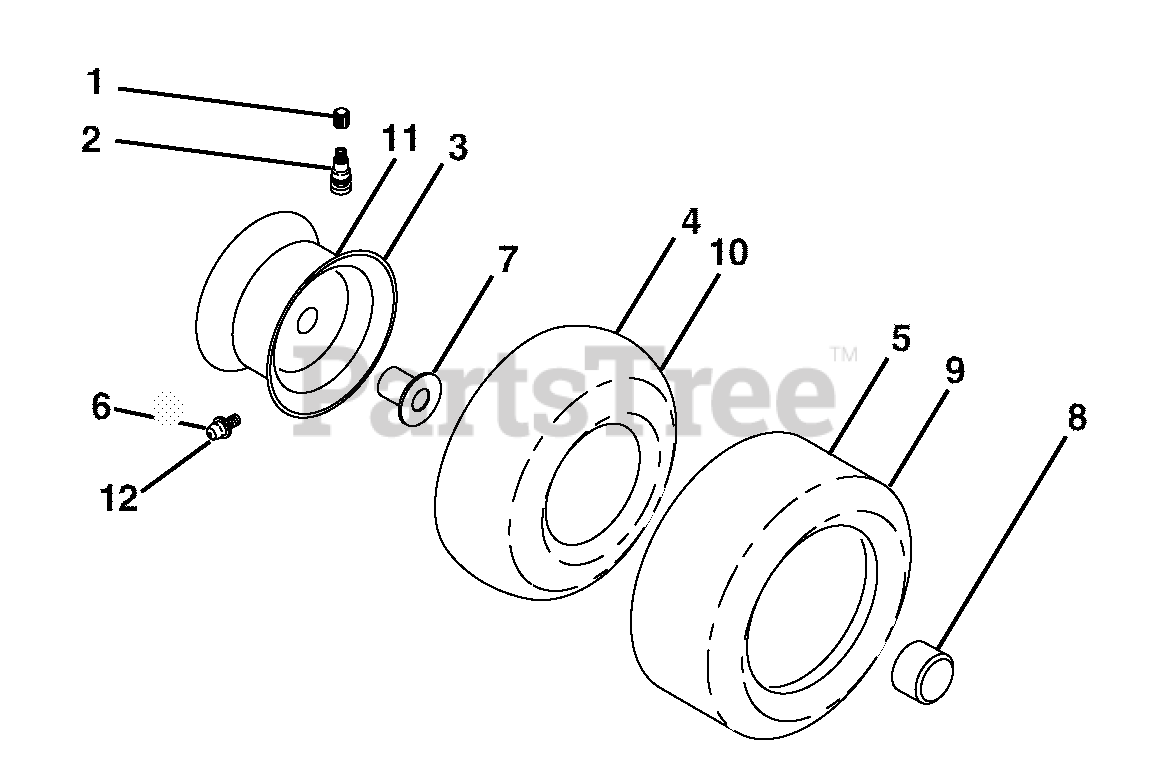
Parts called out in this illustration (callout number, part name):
1	Cap, Valve, Tire
2	Stem, Valve
3	Rim Assembly, Front
4	Tube, Front
5	Tire, Front
6	Fitting, Grease
7	Bearing, Flange
8	Cap, Hub
9	Tire, Rear
10	Tube, Rear
11	Rim Assembly, Rear
12	Fitting, Grease
